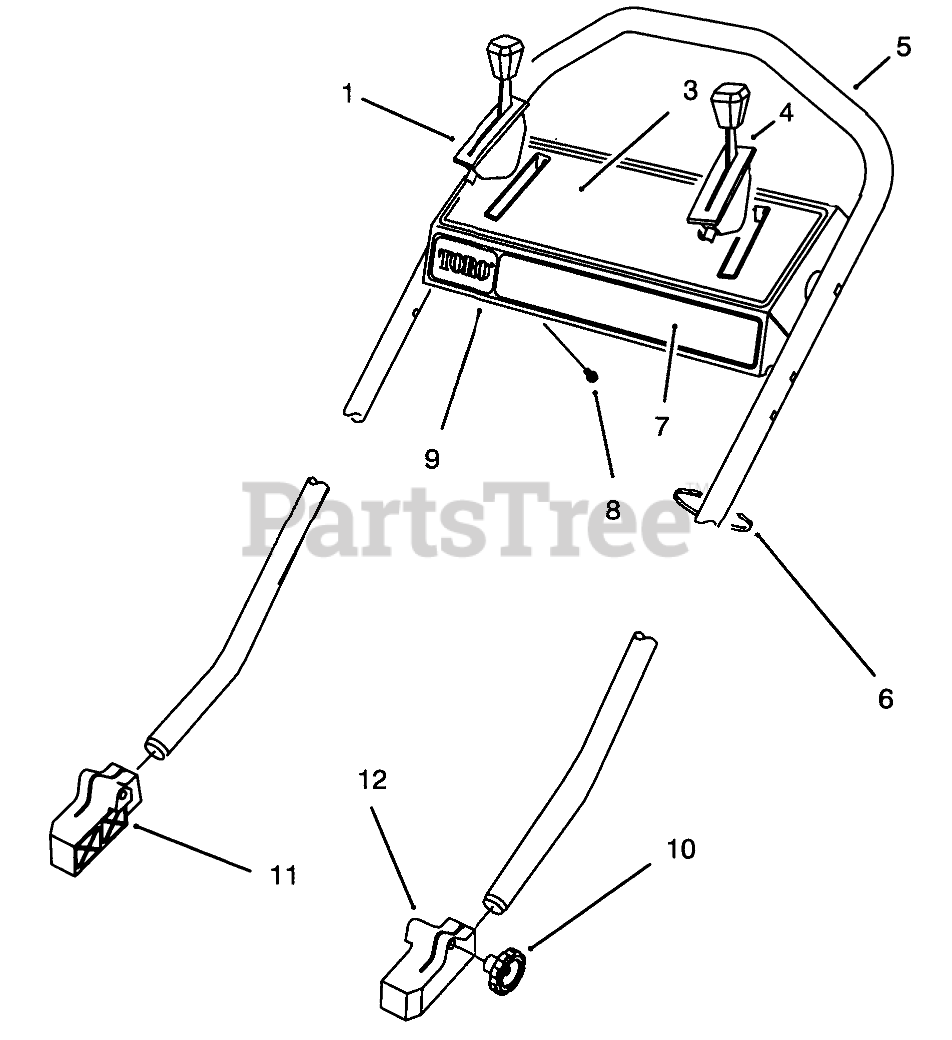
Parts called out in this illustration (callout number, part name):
1	GROUND SPEED CONTROL
3	DECAL-INSTRUCTION BBC
4	THROTTLE CONTROL
5	HANDLE PVC DIP
6	TIE-CABLE
7	DECAL - PANEL BBC
8	SCREW-HWHTF
9	Control Panel Assembly (Incl. Ref. #3 & 7)
11	MOUNT-HANDLE, RH
12	MOUNT-HANDLE, LH
